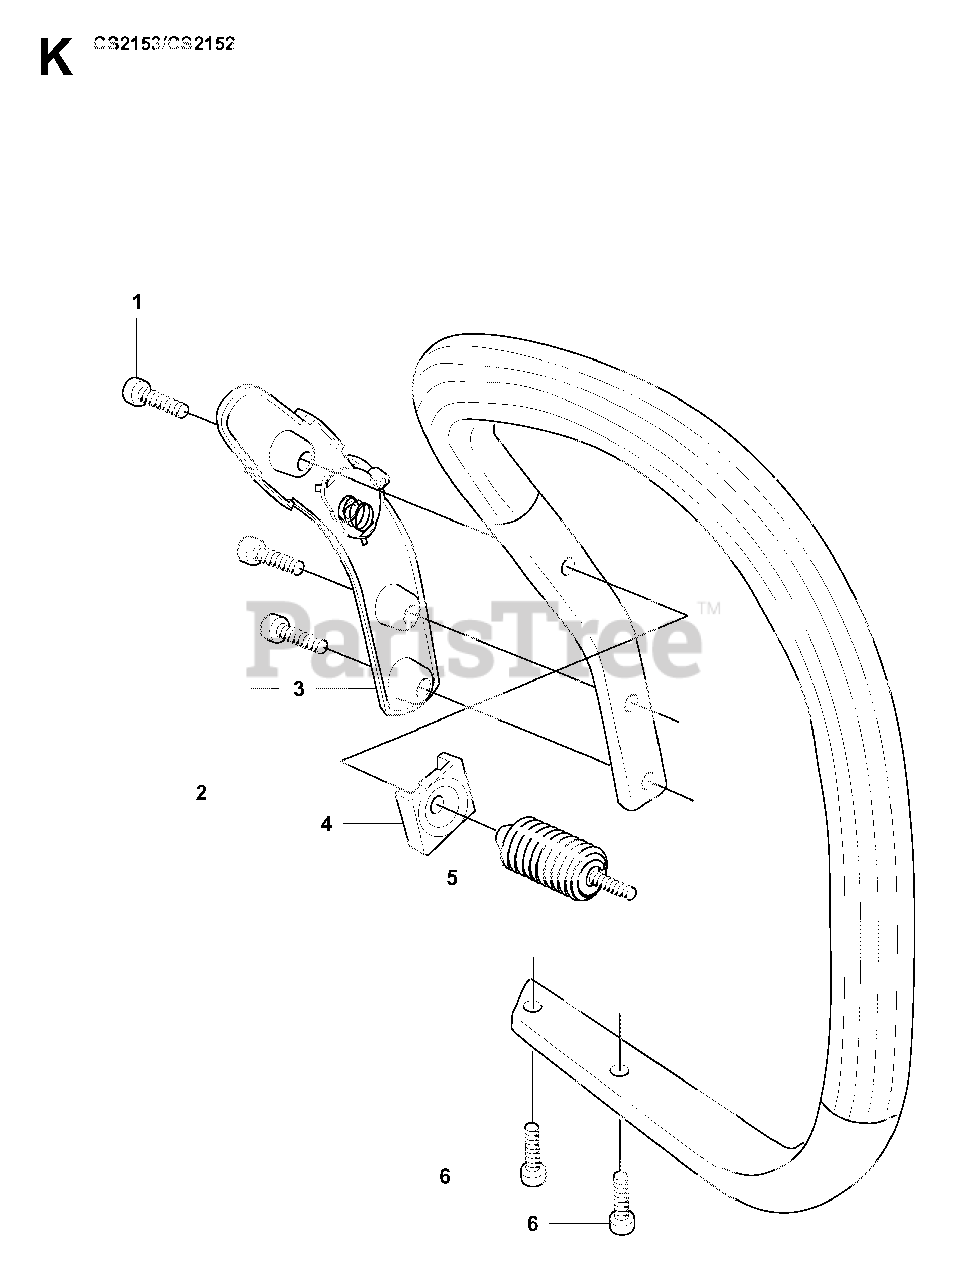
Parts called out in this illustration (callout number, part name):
2	FRONT HANDLE
5	INSULATOR
6	SCREW IHSCFT
